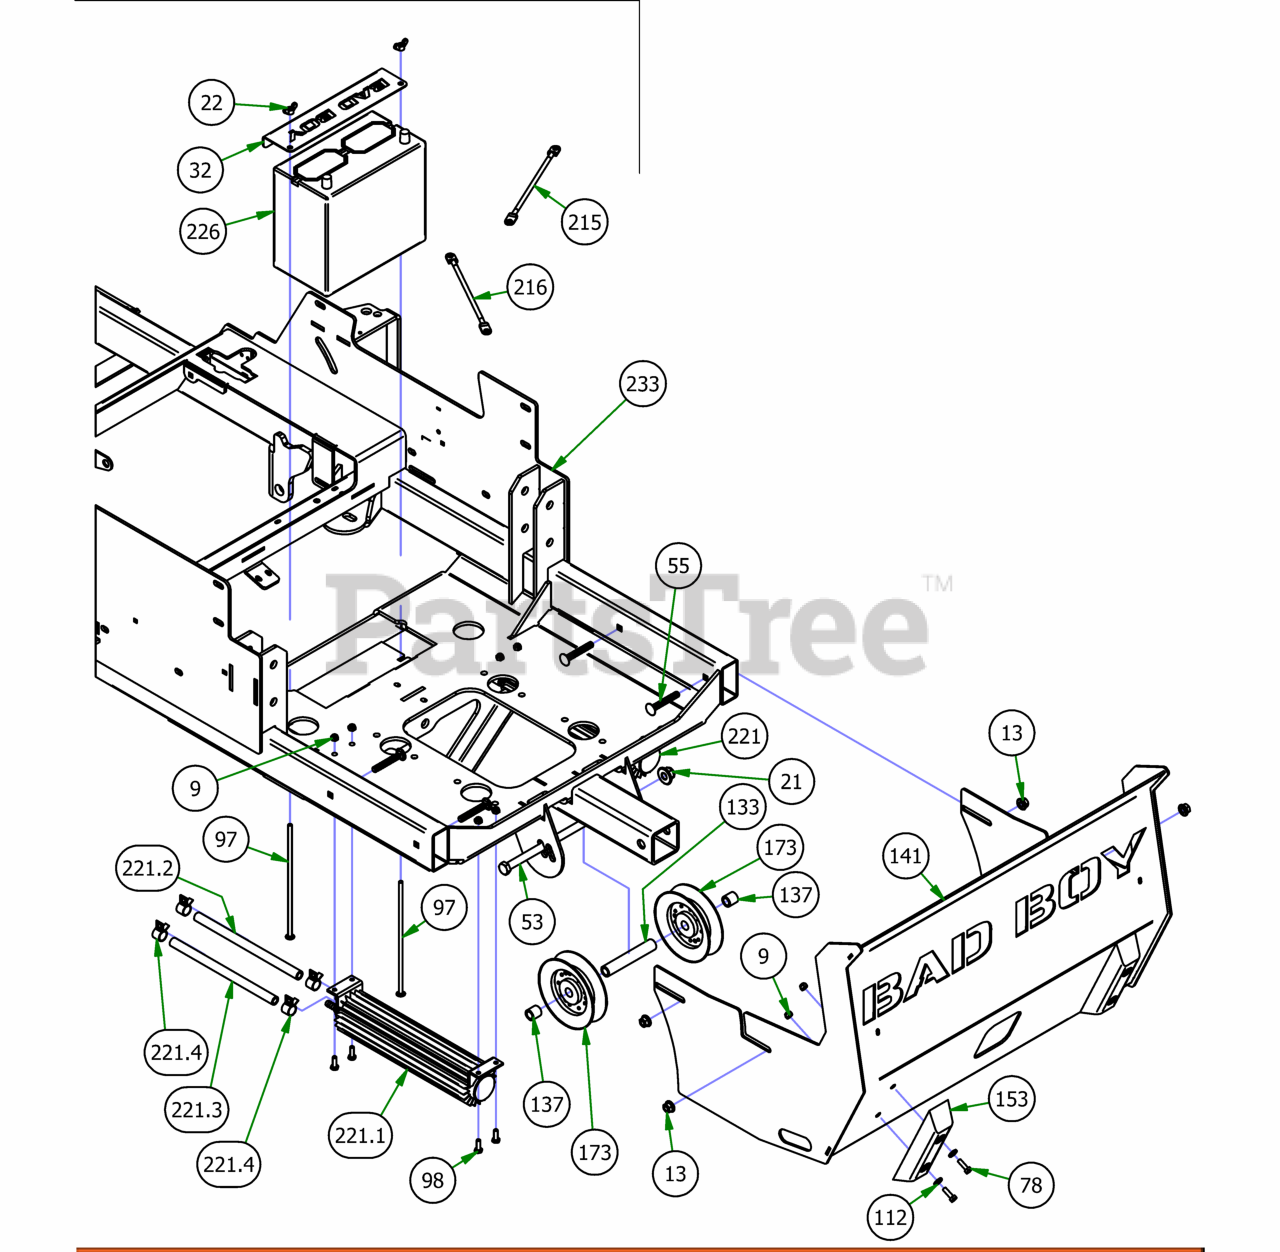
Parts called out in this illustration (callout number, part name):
9	1/4-20 Hex flang lock nut
13	3/8-16 NYLON INSERT FLANGE LOCKNUT (GR.F) ZINC
21	1/2-13 NYLON INSERT FLANGE LOCKNUT ZINC
22	1/4" Wing Nut
32	2019 Horizontal Battery Hold Down Cover
53	1/2" x 8 1/2 GR 5 Hex Bolt
55	3/8" x 2 1/2" Carriage Bolt
78	1/4-20 x 1-1/4 GR 5 Hex Bolt
97	1/4" x 1" Carriage Bolt
98	1/4" x 3/4" Hex Bolt
112	1/4" Flat Washer
133	2019 Pulley Spacer .75 x .5 x 4.375
137	Spacer 3/4 OD x 1/2 ID x 3\4 Length
141	2019 Horizontal Suspension Rear Cover
153	8" Rubber Bumper
173	2019 Outlaw Horizontal Rear V Pulley
215	Red Battery Cable - Diesel
216	Black Battery Cable - Diesel
221	Renegade Oil Cooler Assembly
221.1	2019 12" Oil Cooler With Fittings
221.2	3/8" Clear Hose
221.3	3/8" Clear Hose
221.4	3/8" Hose Clamp
226	Battery - Diesel/Renegade Models PF-516
233	2019 Renegade Diesel Frame - Powdercoated
